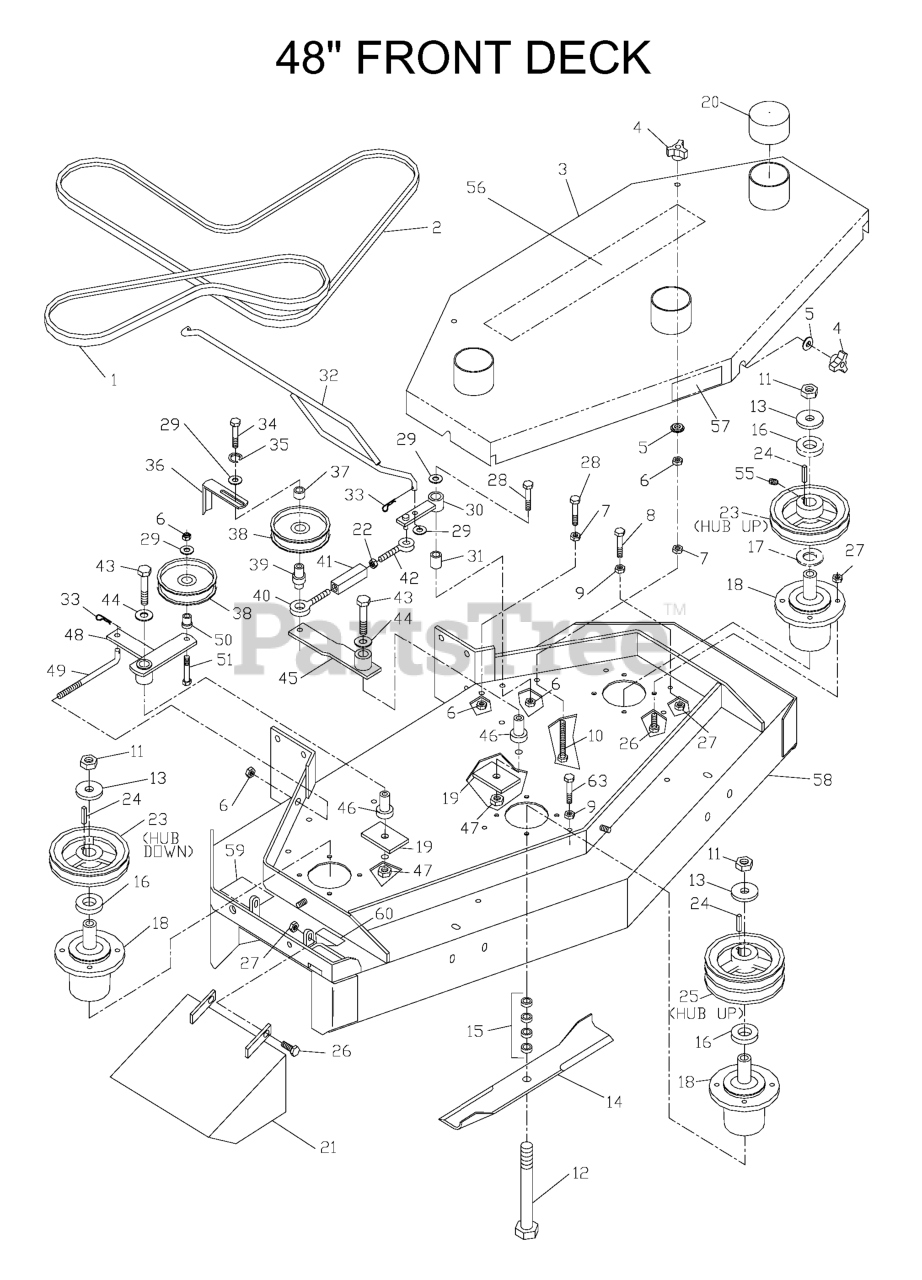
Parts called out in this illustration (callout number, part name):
1	BELT, AUX BLADE
2	BELT - ENG/DECK 48
3	BELT SHIELD 48"
4	KNOB, THREE PRONG
5	WASHER, 3/8 SEALING
6	NUT 3/8C CENTERBLOCK
7	NUT 3/8C WHIZ
8	HCS 5/16 X 3
9	NUT 5/16C WHIZ
10	TAPBOLT 3/8C X 4 1/2
11	NUT 5/8F HEX
12	HCS 5/8F X 8 1/2
13	WASHER, SUPPORT
14	BLADE OEM 16 1/4"
15	BLADE SPACERS
17	MACHINERY BUSHING 10 GA.
18	HOUSING ASSEMBLY
21	DEFLECTOR CHUTE
22	NUT 5/16C HEX
23	PULLEY W/SETSCREWS
24	KEY 1/4 SQ X 1 1/8
25	PULLEY, DOUBLE W/SETS
26	HCS 5/16C X 1
27	NUT 5/16C CENTERLOCK
28	HCS 3/8C X 2 1/4
29	WASHER 3/8 FLAT
30	ENGAGEMENT ARM
31	BUSHING, SLEEVE
32	LOWER LINK
33	HAIRPIN #2
34	HCS 3/8C X 2 1/2
35	SLW 3/8 STD
38	IDLER PULLEY
39	EYEBOLT PIVOT
40	EYEBOLT, LH
41	TURNBUCKLE
42	EYEBOLT, RH
43	HCS 1/2C X 2 3/4
44	WASHER 1/2 FLAT
45	ARM WELDMENT
46	IDLER SPINDLE
47	NUT 1/2-13 HEX NYLOC ZD
48	IDLER ARM, AUX.
49	TENSION ROD
50	BUSHING, IDLER FLANGE
51	HCS 3/8-16 X 1 3/4 GR5
55	SET SCREW 5/16 NYLOC
56	DECAL, HUSQVARNA 17.5"
57	DECAL, NASCAR
58	DECK W/DECALS 48"
59	DECAL, DANGER
60	DECAL, CPSC
63	HCS 5/16C X 4
539101100	HCS 5/8-18 X 9 GR5 ZD
